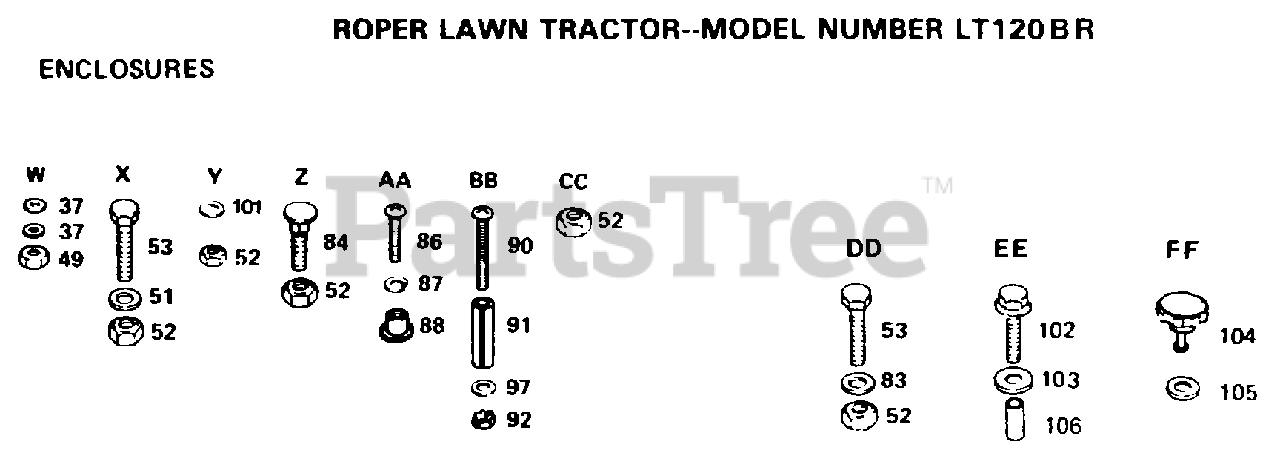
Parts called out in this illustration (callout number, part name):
37	WASHER PM
51	WASHER
53	BOLT
83	WASHER
84	BOLT
86	SCREW
87	LOCKWASHER
88	WELDNUT
90	SCREW
91	SPACER LT
97	WASHER
101	WASHER
102	BOLT T
104	"KNOB 1/2"" YT"
